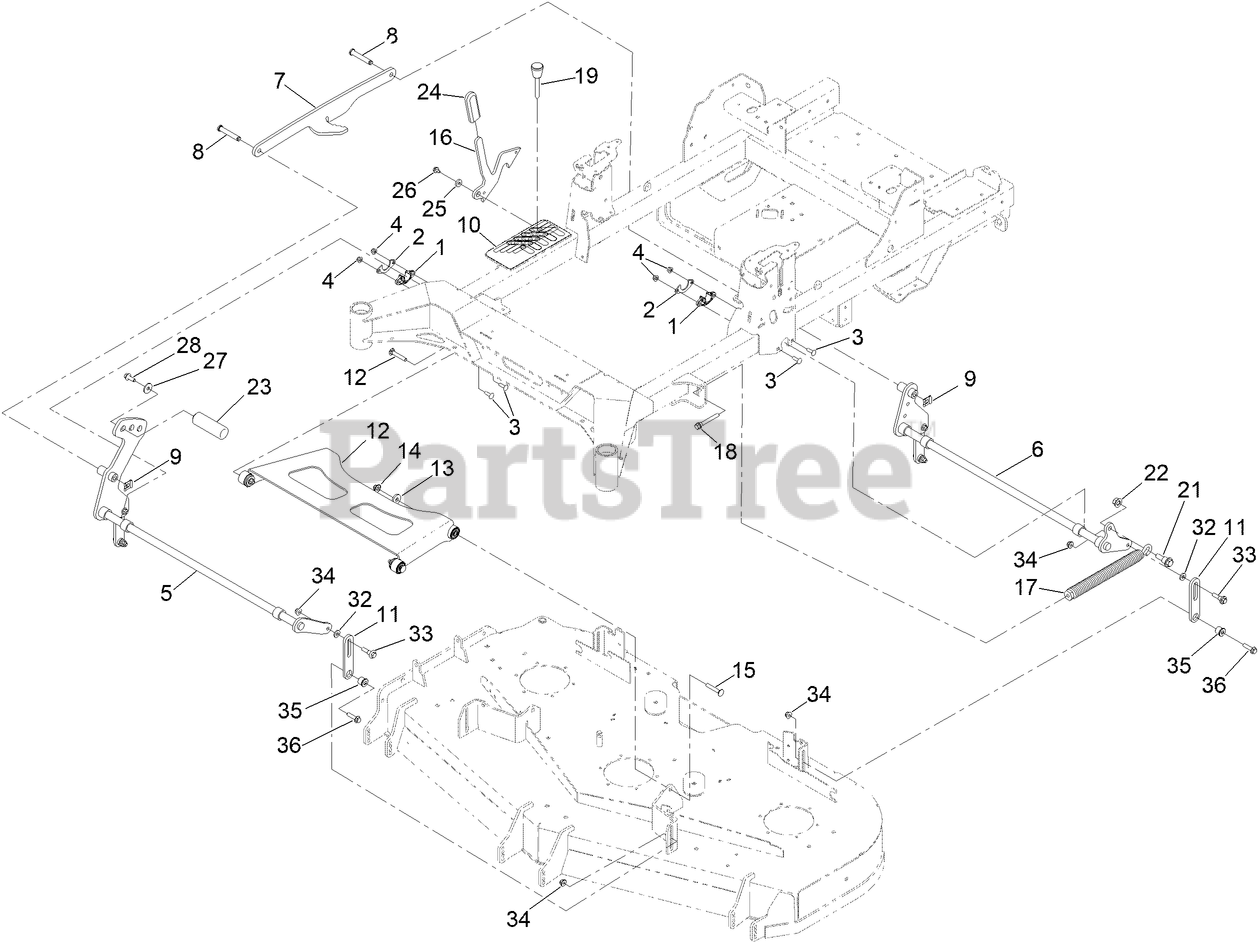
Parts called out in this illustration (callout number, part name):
1	BEARING-FLANGE
2	GUSSET-LIFT, DECK
3	SCREW-CARR
4	NUT-HF, NI
5	DECK LIFT SHAFT ASM, FRT [BLACK
6	DECK LIFT SHAFT ASM [BLACK]
7	LINK-LIFT
8	PIN-CLEVIS
9	CLIP-PIN
10	DECAL-HOC
11	LINK-LIFT, DECK
12	ASM-DECK STRUT W/ BUSHINGS
13	WASHER
14	NUT-FLANGE, NI
15	SCREW-CARR
16	PLATE-TRANSPORT LOCK
17	SPRING-EXTENSION
18	BOLT-SHOULDER
19	PIN-HOC
21	SCREW-SHOULDER, HHF
22	NUT-LOCK
23	PEDAL-FOOT LIFT
24	GRIP-LEVER
25	SPACER
26	SCREW
27	WASHER
28	SCREW-HHF
32	SPACER
33	BOLT-SHOULDER
34	NUT-HF, NI
35	BUSHING-DECK LIFT
36	SCREW-HHF
